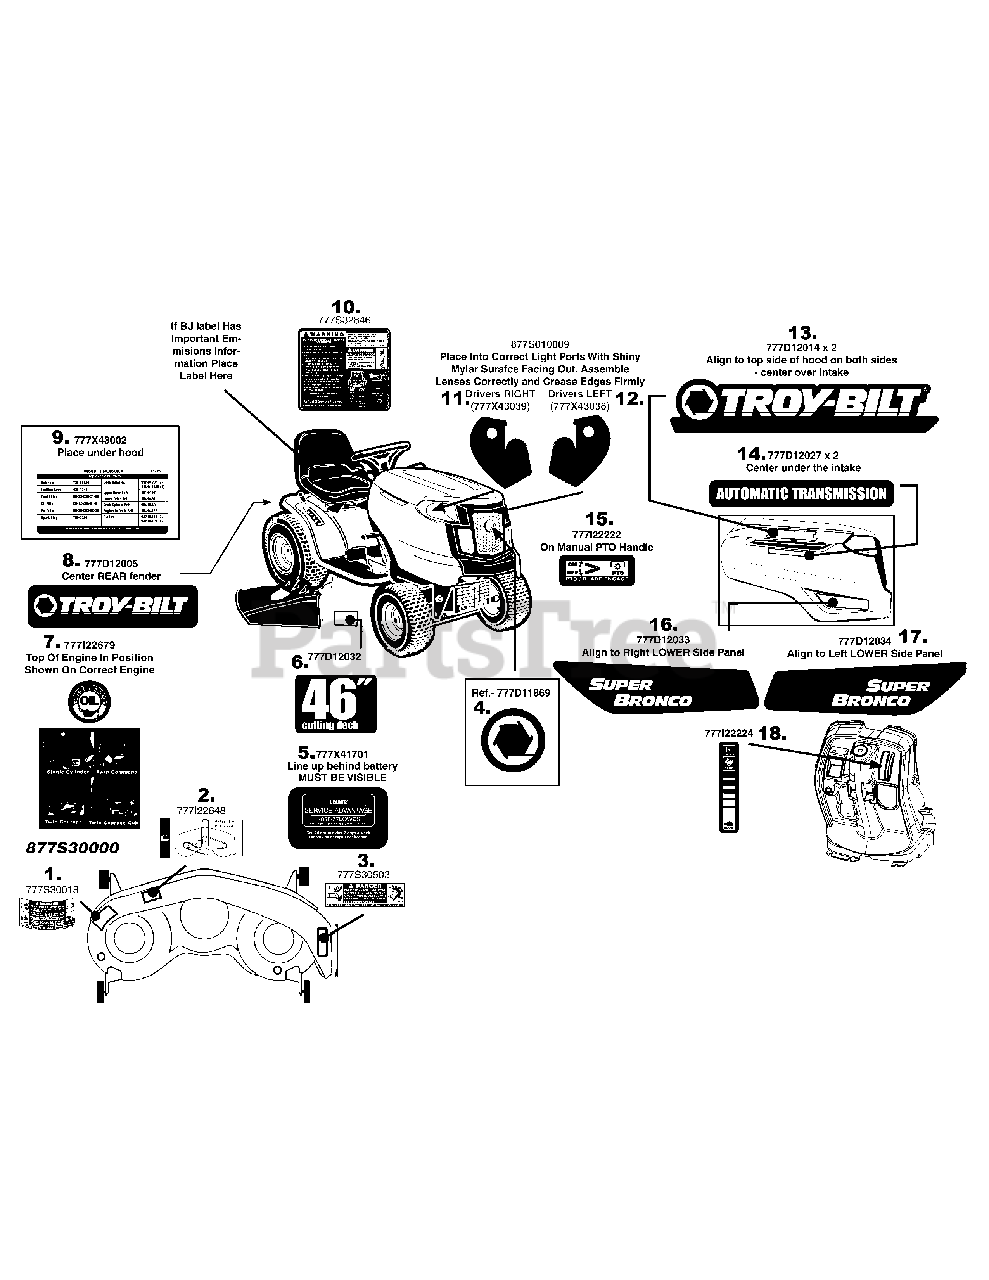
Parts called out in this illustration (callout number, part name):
1	LABEL-DECK SAFETY
2	LABEL-DECK BELT ROUTE
3	LABEL-DANGER CHUTE
4	LABEL-EMBOSSED TROYBILT
6	LABEL-RIDER DECK TROY 46"
7	LABEL-CHECK ENG OIL
8	LABEL-RIDER REAR FENDER TROY
9	LABEL-RIDER PARTS LIST 13AX60KH
10	LABEL-RIDER SAFETY:CRUISE
11	LABEL-RIDER K STYLE RH
12	LABEL-RIDER K STYLE LH
13	LABEL-RIDER HOOD K STYLE TROY
14	LABEL-RIDER K STYLE HOOD AUTOTRANS
15	LABEL-PTO HANDLE
16	LABEL-RIDER HOOD K STYLE TROY
17	LABEL-RIDER HOOD LH K STYLE TROY
18	LABEL-DASH RH
